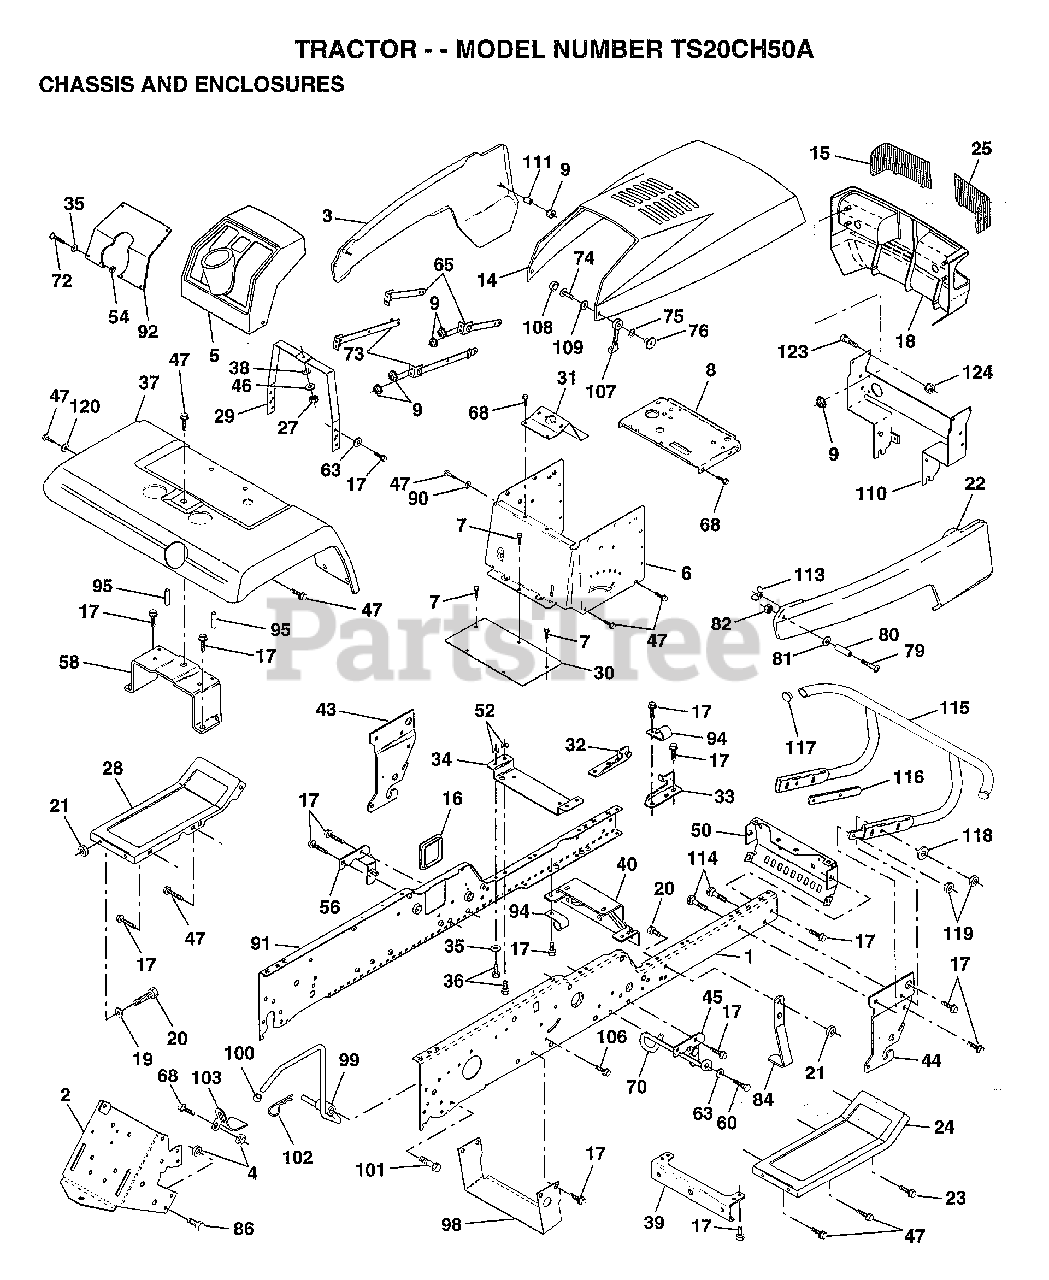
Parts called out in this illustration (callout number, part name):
2	DRAWBAR GT
4	NUT.7/16
5	DASHBOARD BLACK
6	DASH.1PC.LOWER
7	SCREW
8	SUPPORT.DASH.BTRY
9	PAL NUT LT
15	LENS.BAR.CLEAR
16	COVER ACCESS
17	SCREW
19	WASHER
20	BOLT
21	NUT
22	PANEL SIDE RH
23	SCREW GTV
24	FOOTREST.RH.LT/GT
28	FOOTREST.LH.LT/GT
29	DASH.SUPT.YP/HUSQ
30	SADDLE.HYDRO.95
31	BRAKET.SUPT.STEER
32	BRACKET ASM FRAME
33	BRACKET ASM FRAME
34	BRACKET.ENG.SUPT.
35	WASHER
36	BOLT
37	FENDER.PNT.
38	WASHER PM
39	BRACKET.AXLE.FRT.
43	BRACKET.SUS.FT.LH
44	BRACKET.SUS.FT.RH
46	LOCKWASHER
47	SCREW LT
50	BRACKET.CHASSIS.
51	SCREW CRT
57	NUT
58	BRKT.ASM.FENDER
60	SCREW
63	WASHER
65	STRAP.ASM.HINGE.
68	SCREW LT
70	GUIDE.BELT.MID.SP
71	STRAP.GRILLE.PNT.
72	SCREW
73	STRAP.ASM.HINGE.R
74	SCREW
75	LOCKWASHER
76	WELDNUT
79	SCREW
80	SPACER LT
81	WASHER
84	STOP.OVER.CENTER
86	BOLT
90	LOCKWASHER
92	PLATE YP SLKSCR
94	CLIP GTV
95	NUT-PUSH YT
98	BRACKET SKID CHAS
99	ROD BYPASS
101	SCREW LT
102	RETAINER M
103	LOCK BYPASS BRKT
107	HOOD LATCH T
114	BOLT.3/8-14X1.25
115	BUMPER.ASM.W/PY
116	BRACKET.EXT.BUMP.
117	PLUG.PLASTIC
118	WASHER
120	WASHER HYT
124	NUT
